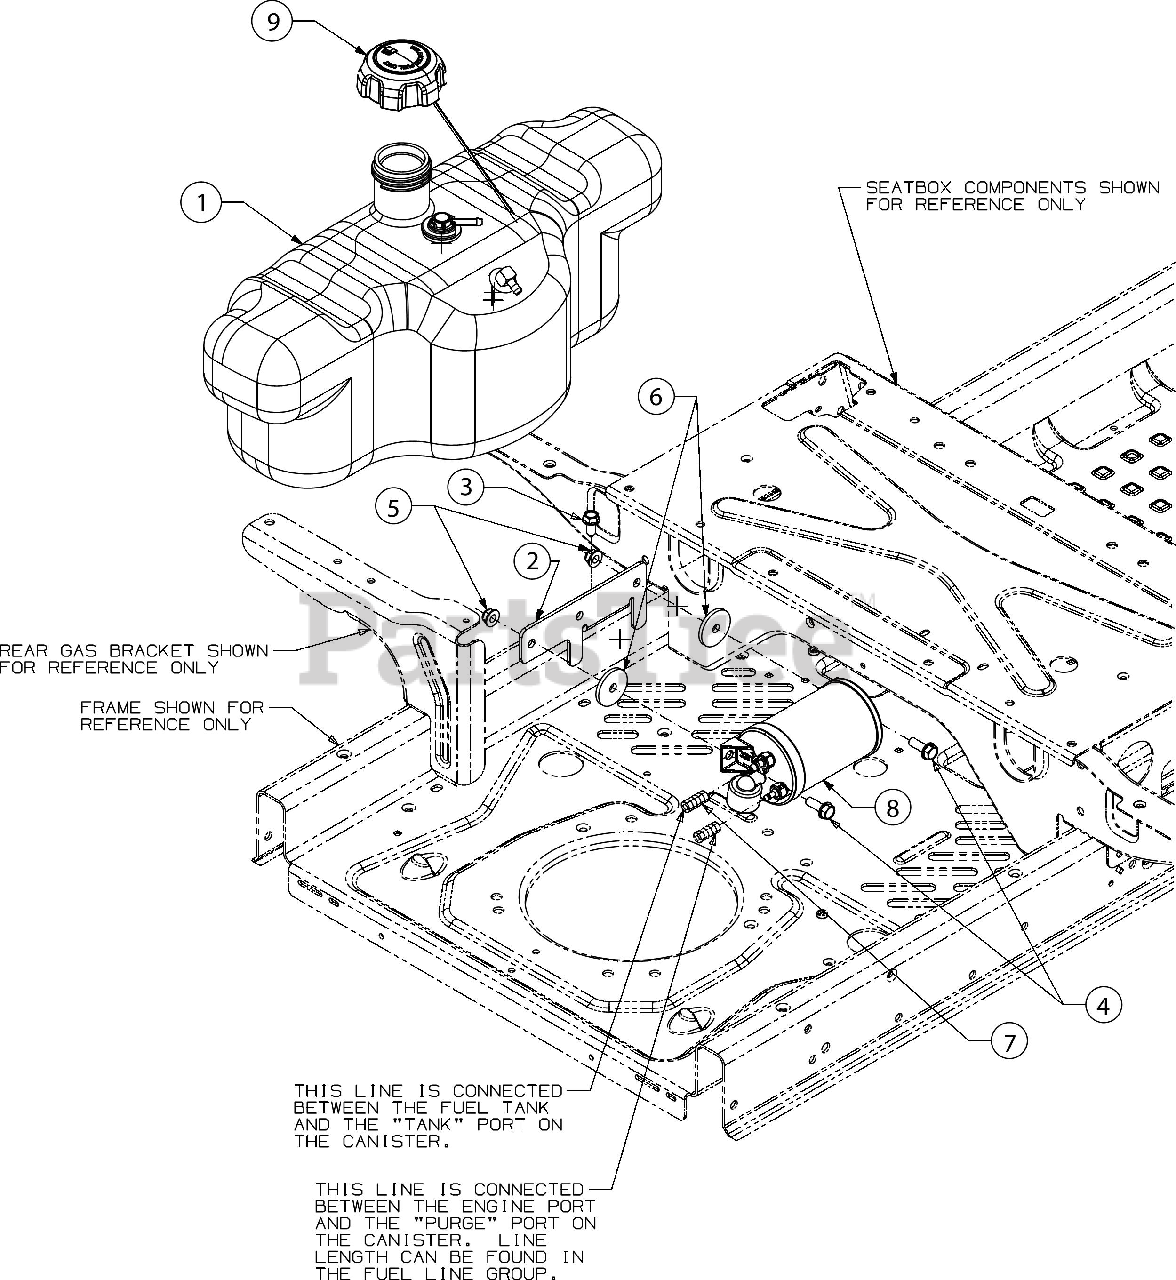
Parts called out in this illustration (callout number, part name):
1	FUEL TANK ASSEMBLY
1	RUBBER GROMMET 23.0 ID x 35.5 OD
1	FUEL PICKUP FITTING
1	ROLLOVER FUEL VALVE
3	SCREW 5/16-18 x .750
4	SCREW 5/16-18 x .875 GR5
5	FLANGE LOCK NUT 5/16-18
6	FLAT WASHER
7	FUEL HOSE LO PERMEATION
8	CARBON CANISTER
9	FUEL CAP W/TETHER
